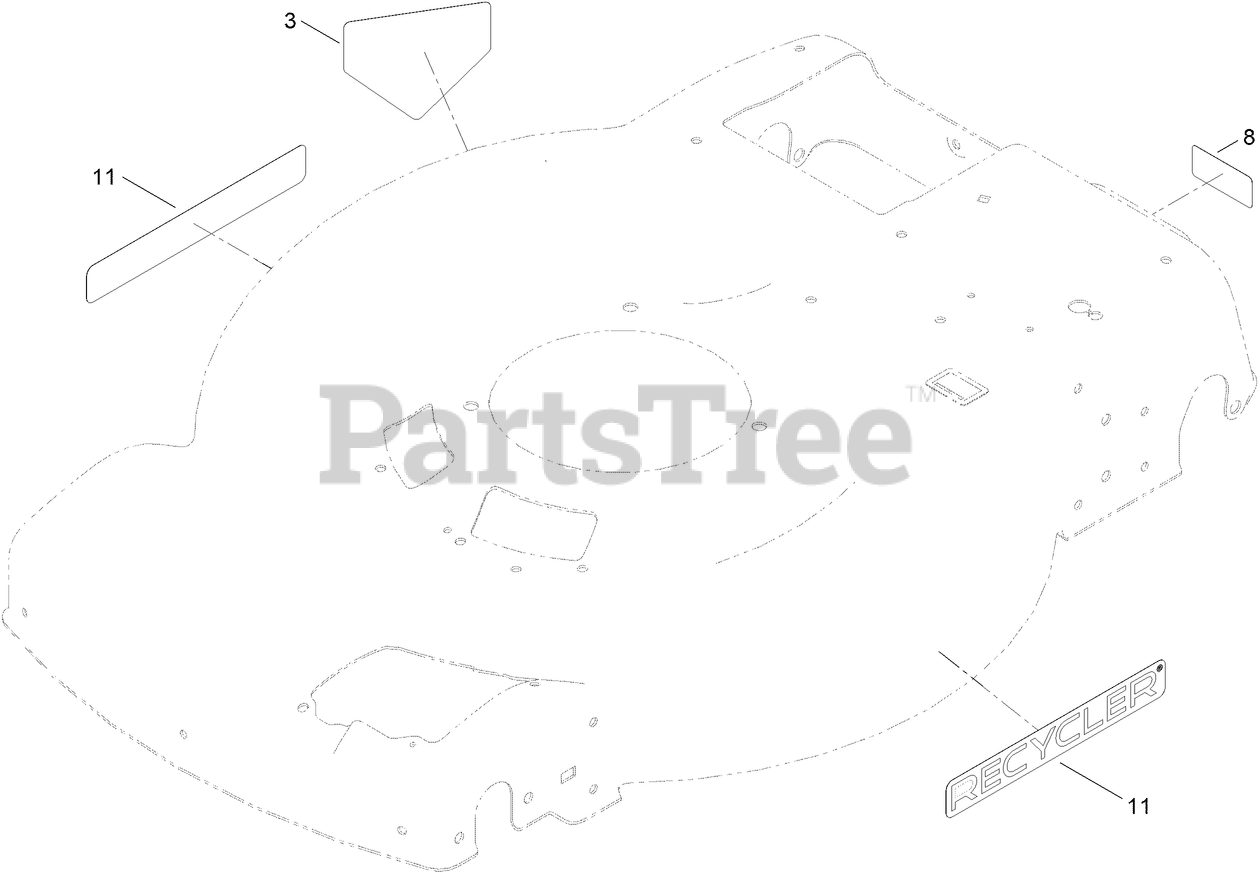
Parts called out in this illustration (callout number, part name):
3	DECAL-DANGER
8	DECAL-LOCATION, SERVICE DEALER
11	DECAL-RECYCLER MAX
